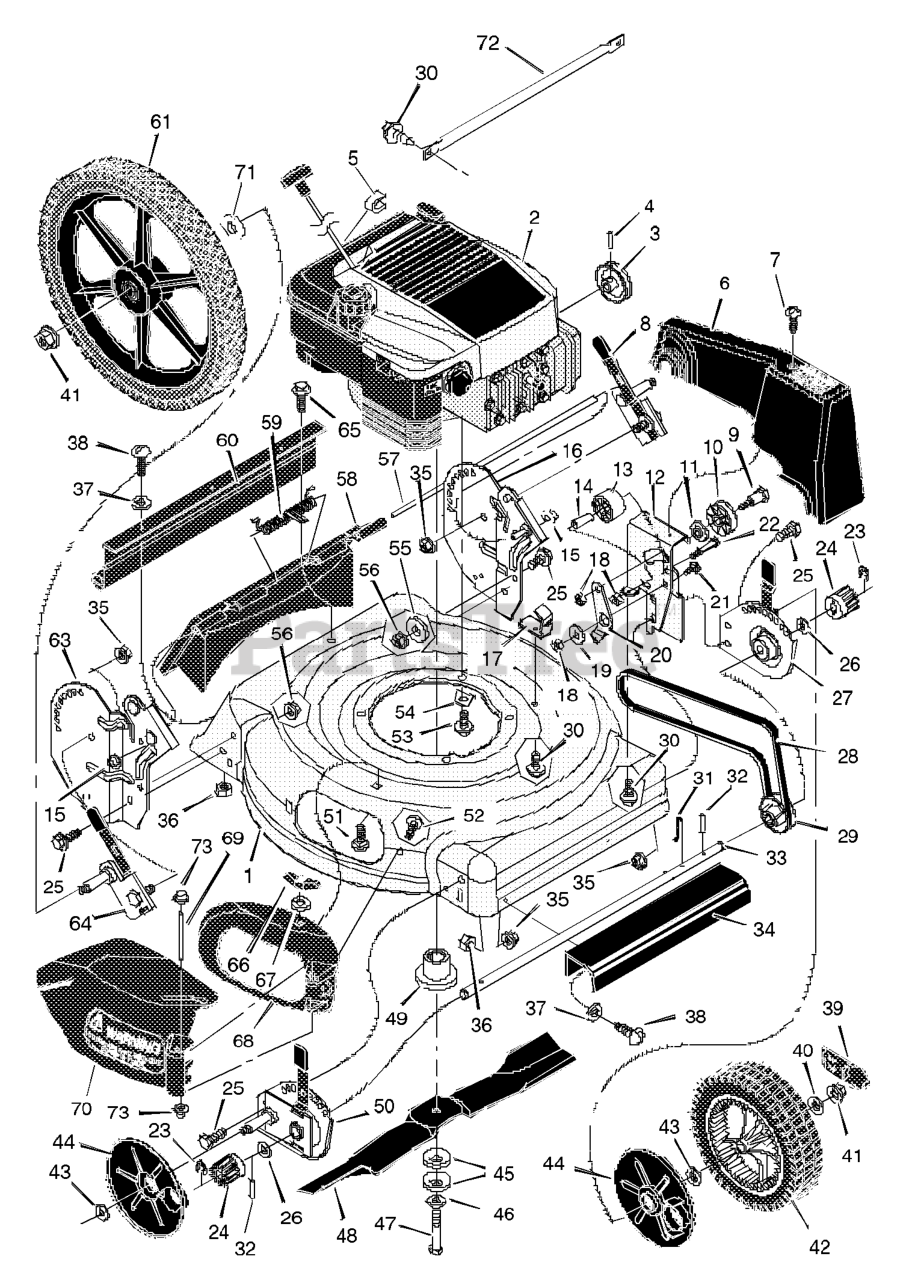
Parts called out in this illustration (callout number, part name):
1	Housing
2	Engine *
3	Pulley, Engine
4	Pin, Spring
5	Stop, Rope (Recoil - Start)
6	Cover, Belt
8	Adjuster, Left Height
9	Bolt, Shoulder
12	Bracket, Idler Support
13	Pulley, Idler
14	Bearing
15	Push On Cap
16	Bracket, Left Handle
17	Bracket, Cable
18	Nut, Hex
20	Arm, Idler
21	Bolt, Carriage
22	Bolt, Shoulder
24	Gear, Pinion
25	Bolt
27	Adjuster, Left Front Height
29	Pulley, Axle
31	Pin, Hair
32	Pin, Spring
34	Cover, Axle
35	Nut, Flange
36	Nut, Hex
39	Hub Cap
40	Washer
41	Nut, Flange
42	Wheel, Drive *
44	Cover, Dust
45	Washer, Belleville
49	Adapter, Blade
50	Adjuster, Right Front Height
51	Bolt, Carriage
53	Bolt, Engine
54	Support, Engine
55	Washer
56	Nut, Flange
57	Rod, Pivot
58	Door, Rear
60	Guard, Rear
61	Wheel, Rear *
62	Nut, Flange
63	Bracket, Right Handle
64	Adjuster, Right Height
66	Wingnut
67	Retainer, Push
69	Pin, Pivot
70	Deflector, Chute
73	Push On Cap
